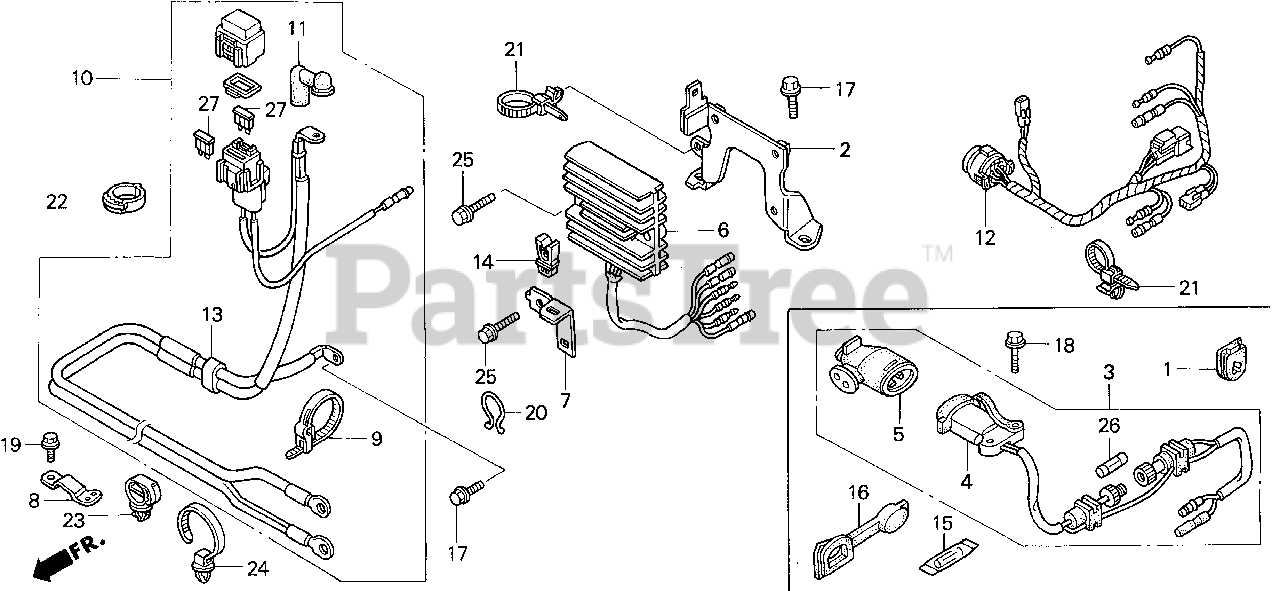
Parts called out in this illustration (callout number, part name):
2	BRACKET, REGULATOR
6	REGULATOR ASSY. (12V) (RECTIFIER)
7	BRACKET, CONNECTOR
8	BRACKET, CABLE CLIP (S)
9	BAND, WIRE
10	CABLE ASSY., STARTER
11	COVER, TERMINAL
13	CLAMP, IGNITION WIRE
14	CLIP B, AIR TEMPERATURE SWITCH WIRE
17	BOLT, FLANGE (6X12)
19	BOLT, FLANGE (5X10)
20	CLIP, PURSE LOCK
21	STRAP, CABLE (118MM) *NH1L* (BLACK)
22	CLIP, WIRE HARNESS
23	CLIP, WIRE HARNESS (25MM)
25	BOLT, FLANGE (6X20)
27	FUSE, BLADE (15A)
